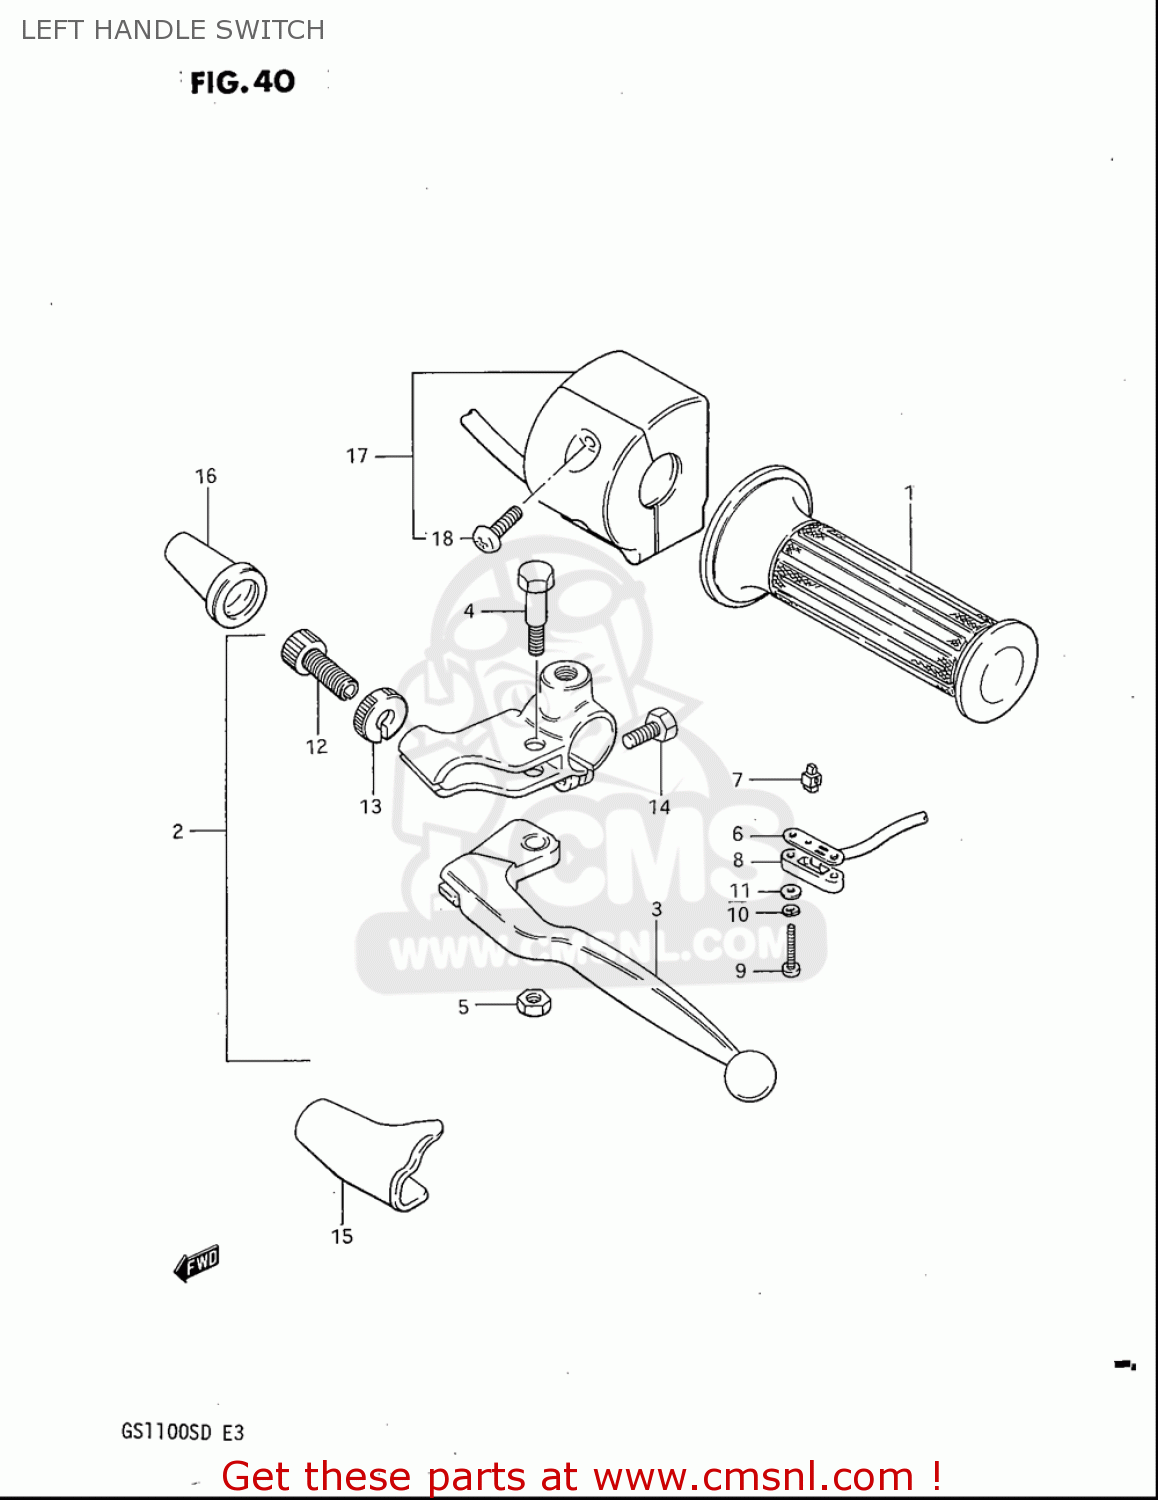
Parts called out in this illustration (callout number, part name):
1	GRIP,L
2	LEVER ASSY,CLUTCH
3	LEVER,CLUTCH
4	BOLT,LEVER PIVOT
5	NUT 6MM
6	WIRE HARNESS,CLUTCH SWITCH
7	CONTACT,SWITCH
8	COVER,FR BK TERMINAL BASE
9	SCREW
10	WASHER,LOCK
11	WASHER
12	ADJUSTER,CABLE
13	NUT,CABLE ADJUSTER
14	BOLT,CLUTCH LEVER HOLDER
15	COVER,CLUTCH LEVER
16	BOOT,CLUTCH CABLE
17	SWITCH ASSY,HANDLE,L
18	SCREW
